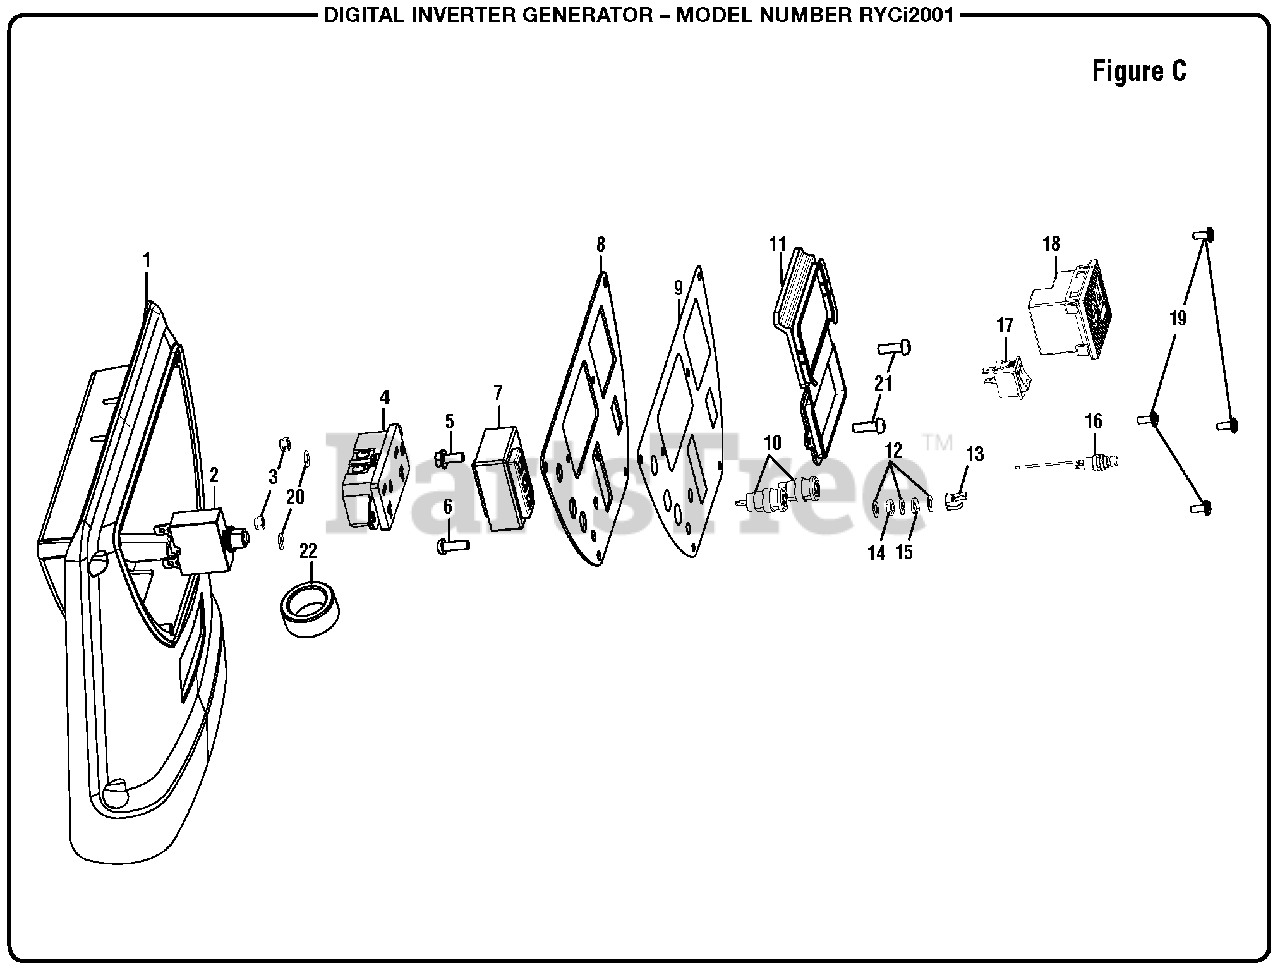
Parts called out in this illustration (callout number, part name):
1	Front Cover
2	Circuit Breaker (20 Amp)
3	Flange Nut (M4)
4	120 Volt Duplex Receptacle
5	Bolt (#10 x 32 mm, Flanged Hd)
6	Screw (M5 x 16 mm, Phillips Pan Hd)
7	Ignition Module
8	Control Panel
9	Front Panel Label
10	Connector
11	120 Volt Outlet Cover
12	Washer (M5 x 10 mm x 05t)
13	Wing Nut (M5)
14	Hex Nut (M5)
15	Lock Washer (OD9 x ID5 x 13t)
16	Reset Button
17	Intelligent Switch
18	Receptacle DC
19	Screw w/Washer (M4 x 10 mm, T20 Torx Button Hd)
20	Washer (OD8 x ID43 x 05t)
21	Screw (M4 x 10 mm, Phillips Pan Hd)
22	Magnetic Ring
